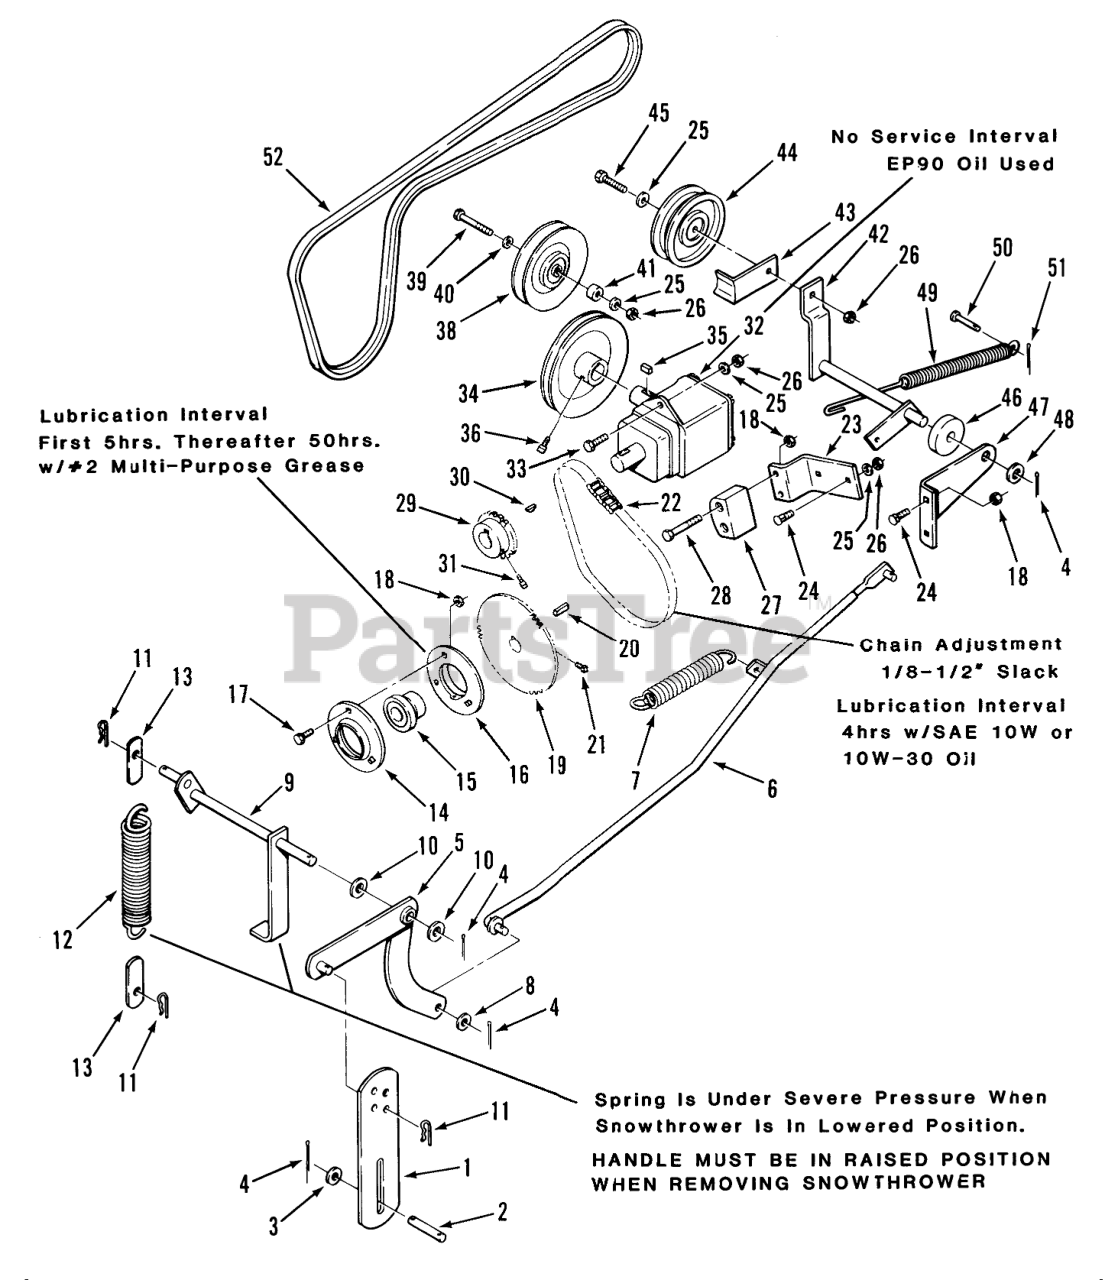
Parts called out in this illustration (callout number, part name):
1	LINK-LIFT R
2	CLEVIS PIN
3	Washer
5	WLDMT-SNOWTHWR LI R
6	WLDMT-LIFT ROD R
7	SPRING
8	SHIM-WASHER
9	WLDMT-SPRING SUPP R
10	Washer
11	Hairpin Cotter
12	SPRING
13	RETAINER-SPRING R
14	Flange
15	BEARING AND COLLAR
16	FLANGE-RELUBE
17	Bolt
18	Nut
19	SPROCKET-33T
20	KEY
21	SCREW-SET
22	CHAIN
23	BRACKET-TIGHTENER R
24	Bolt
25	Washer
26	NUT
27	Chain Tightener
28	Bolt 5/16-18 x 2
29	SPROCKET-15 T
30	KEY-HI PRO
31	Set Screw
32	GEAR-BOX L.H.
33	Bolt
34	Pulley-Gearbox
35	KEY-WOODRUFF
36	Set Screw
38	"V" Pulley
39	Bolt
40	WASHER
41	SPACER
42	WLDMT-IDLER ARM R
43	Spacer
44	PULLEY-FLAT IDLER
45	BOLT
46	RUBBER WASHER
47	BRACKET-PIVOT R
48	WASHER
49	SPRING
50	Clevis Pin
51	Pop Rivet
52	V-BELT 64 .5EL
